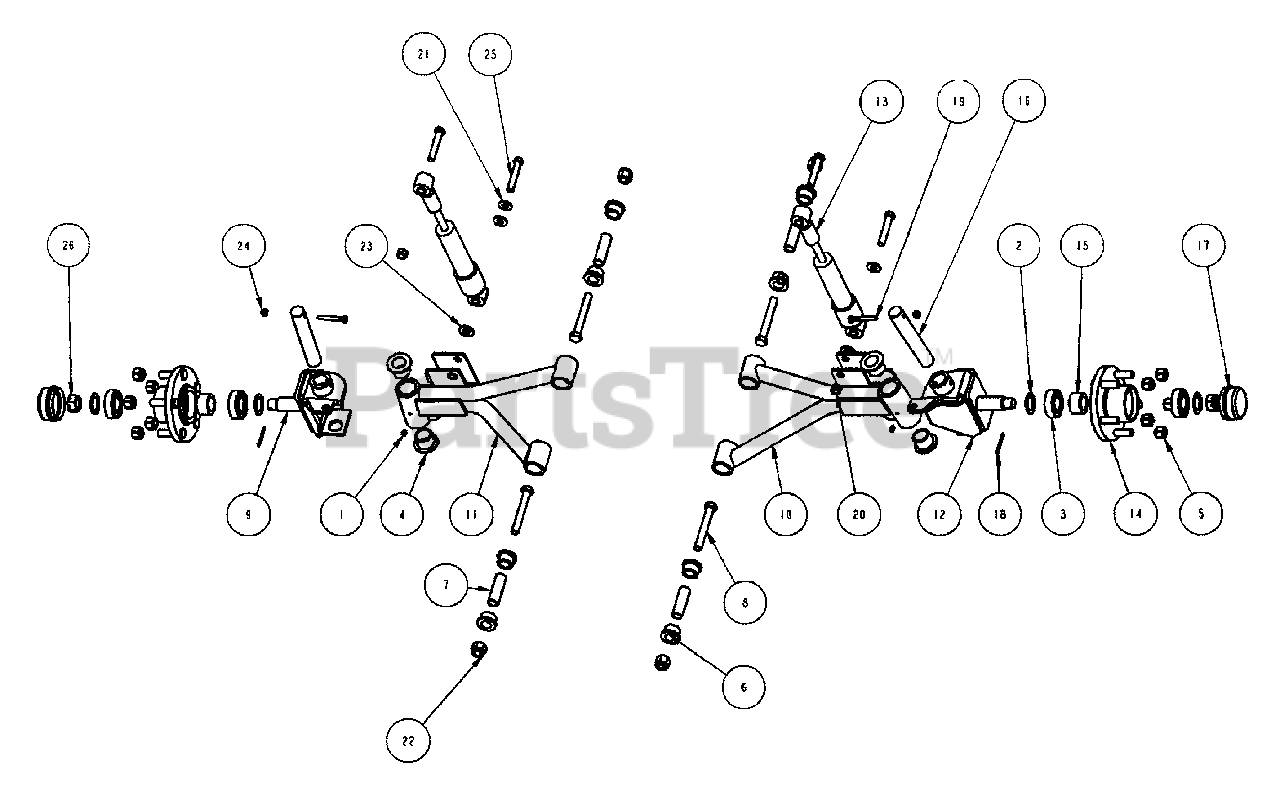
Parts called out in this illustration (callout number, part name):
1	LUBE FITTING, Straight (press-fit for .187 dia. Hole)
2	BUSHING
3	BEARING, BALL, .98" ID, 2.04" OD, .59" Wide
4	BUSHING, CASTER
5	LUG NUT 1/2-20, YZ
6	BUSHING - SUSPENSION
7	SLEEVE - SUSPENSION
8	HHB, 1/2-13 X 3.75
9	WELDMENT, LH SPINDLE
10	A-ARM ASSEMBLY, RH
11	A-ARM ASSEMBLY, LH
12	WELDMENT, RH SPINDLE
13	SHOCK/SPRING ASSEMBLY
14	WHEEL HUB, FRONT
15	SPACER, FRONT WHEEL
16	ROD, SPINDLE PIVOT
17	CASTER SHAFT CAP
18	COTTER PIN, 1/8 X 3/4 YZ
19	HHCS, 1/4-20 X 2 GR5
20	HTLN, 7/16-20
21	FLW, .44 X 1.0 X .08 YZ
22	NUT, 1/2-13 NYLOCK
23	FLW, .531 X 1.062 X .121 YZ
24	1/4-20 HEX NYLON INSERT NUT
25	HHCS 7/16-20 X 1.25 YZ
26	HEX NUT, 7/8-14, YZ
